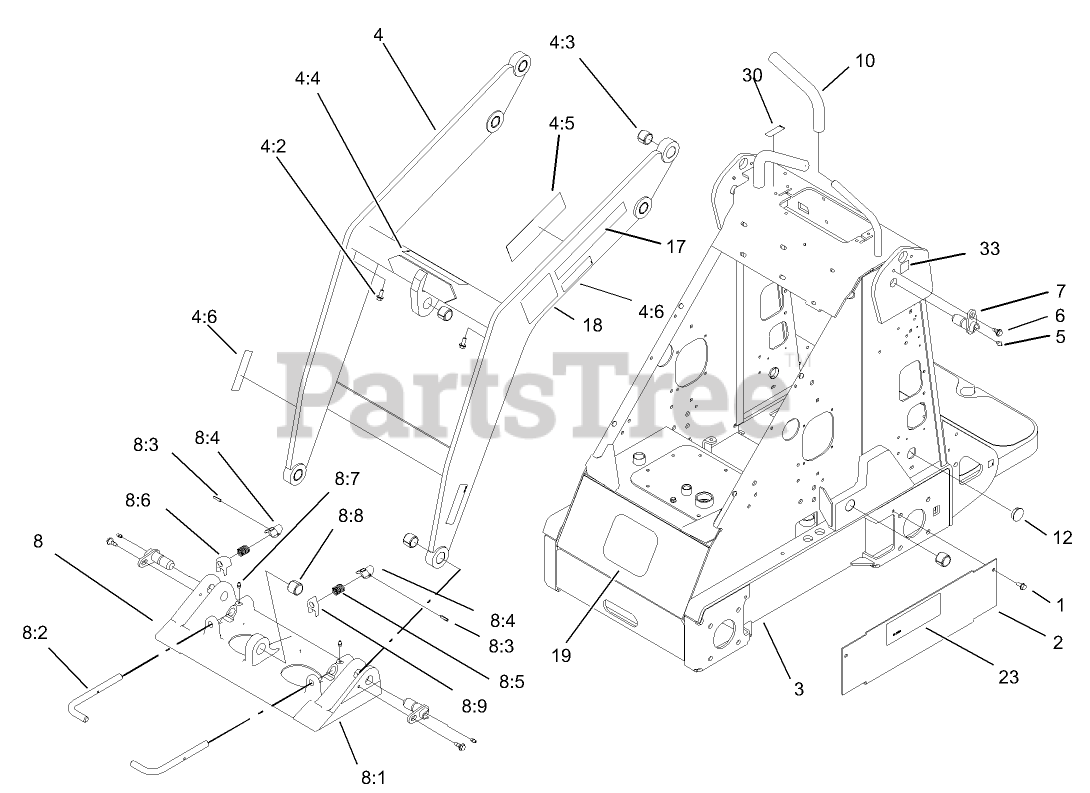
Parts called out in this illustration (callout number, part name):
1	SCREW-HWHTF
2	COVER-HOSE
3	FRAME ASM
4	LOADER ASM
4:2	SCREW-HWHTF
4:3	BUSHING-TENSION
4:4	DECAL-CAUTION
4:5	DECAL-DANGER
4:6	DECAL-PINCH
5	FITTING-GREASE
6	BOLT-SHOULDER
7	PIN-PIVOT
8	QUICK ATTACH ASM
8:1	MOUNT-ATTACH, QUICK
8:2	PIN-LOCKING
8:3	PIN-GROOVED
8:5	SPRING-COMPRESSION
8:6	STOP-RH
8:7	FITTING-GREASE
8:8	BUSHING-TENSION
8:9	STOP-LH
10	GRIP-CUSHION
12	PLUG-HOLE
17	Decal
18	DECAL
19	DECAL
30	DECAL-CHOKE
33	DECAL-POINT, LIFT
